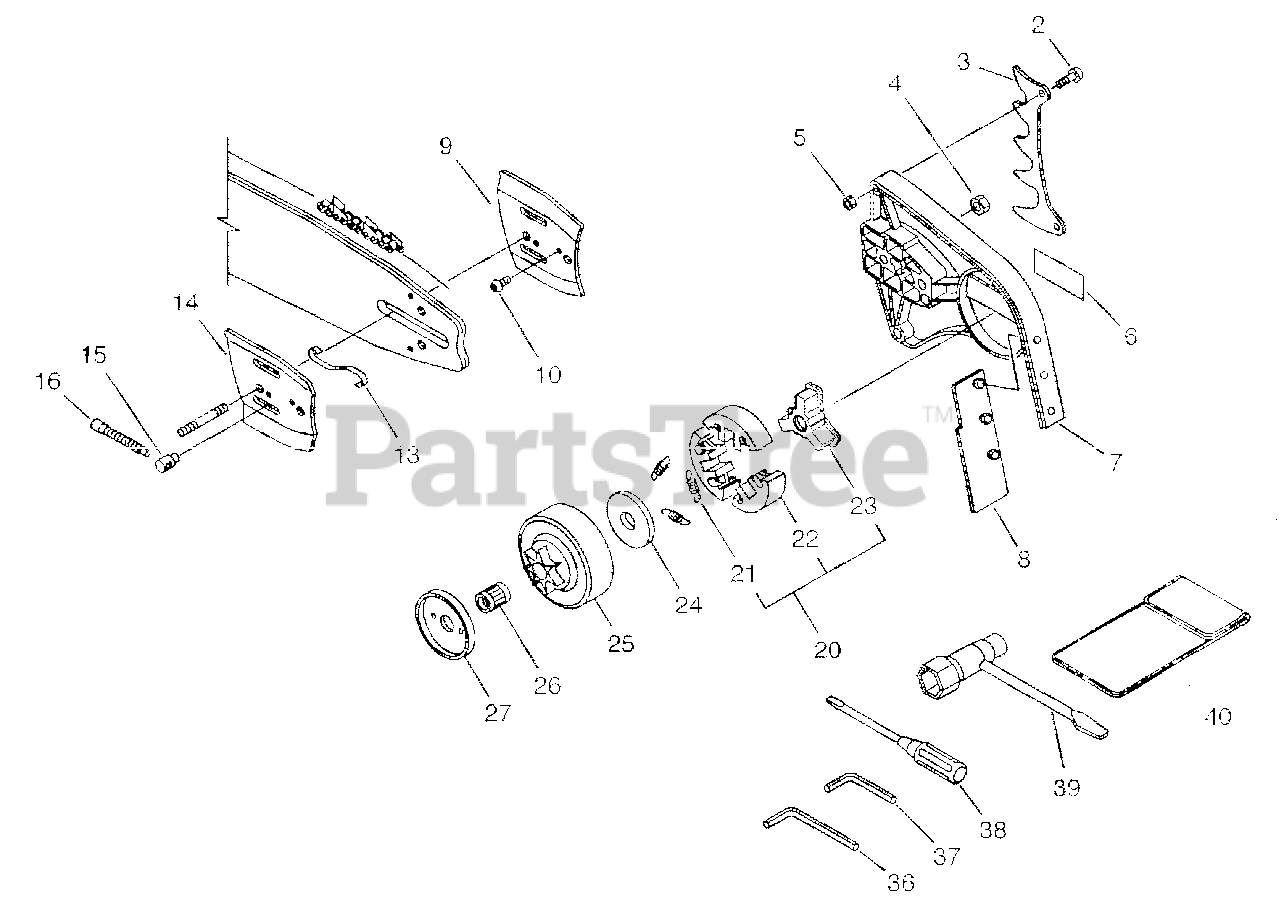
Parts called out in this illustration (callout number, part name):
2	BOLT 6×20
3	SPIKE, BUMPER
4	NUT
5	NUT, LOCK
6	LABEL - ECHO
7	GUARD, SPROCKET
9	PLATE, GUIDE - OUTER
10	SCREW 3×6
13	HOLDER, PLATE
14	PLATE, GUIDE - INNER
15	TENSIONER, CHAIN
16	SCREW, CHAIN TENSION
20	CLUTCH ASSY
21	SPRING, CLUTCH
22	SHOE SET, CLUTCH
23	HUB, CLUTCH
24	PLATE, CLUTCH
25	DRUM, CLUTCH
26	BEARING, NEEDLE
36	WRENCH, ALLEN 5 MM
37	WRENCH, ALLEN 4 MM
38	SCREWDRIVER, SLOTTED
39	WRENCH, T 17×19 MM
40	BAG, TOOL
